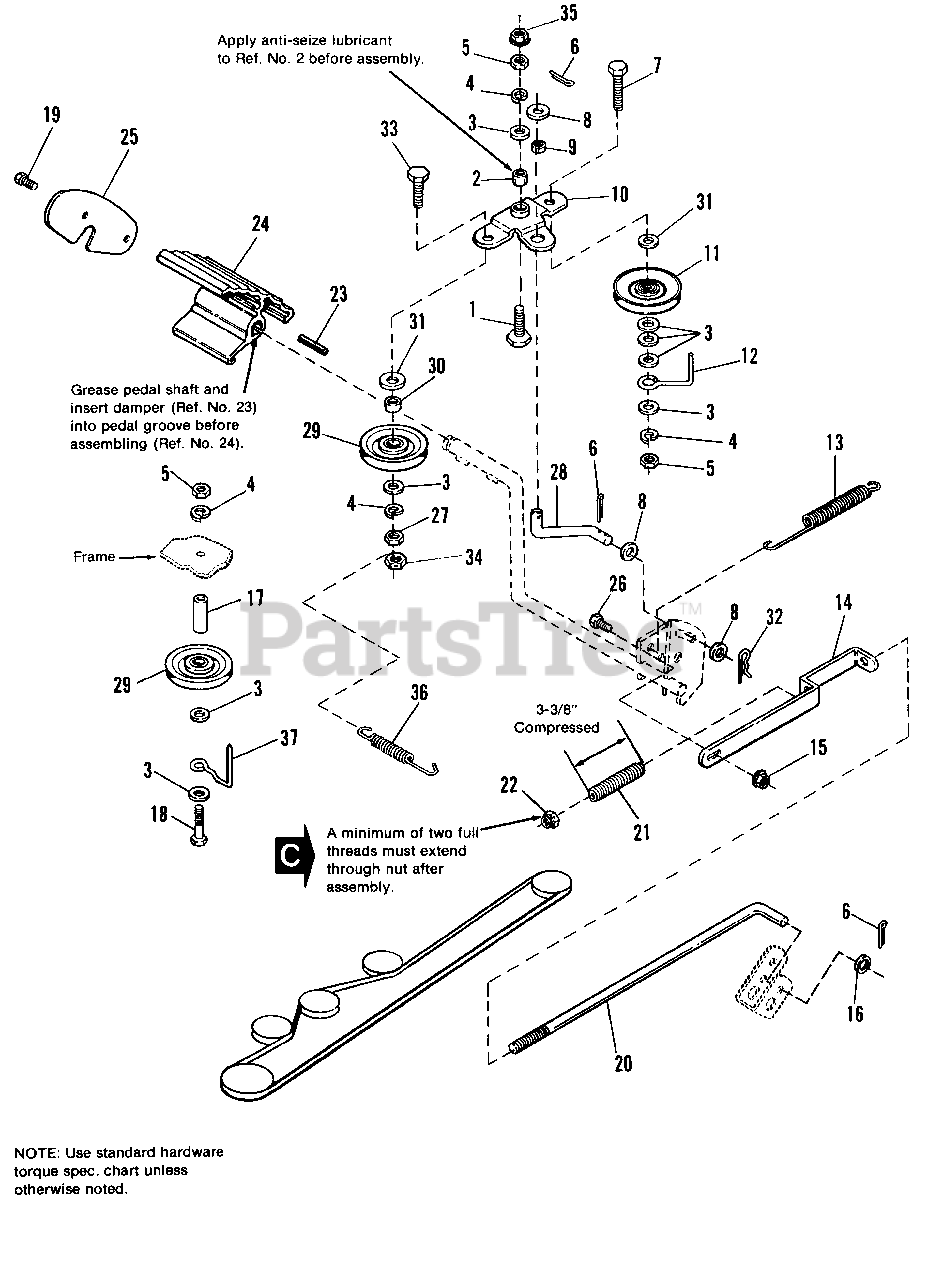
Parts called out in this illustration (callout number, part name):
1	SCREW, Hex, 3/8-16 x 1-1/4, Thin Hd.
3	WASHER, Plain, 5/16
4	LOCKWASHER, 3/8
5	NUT, Hex, 3/8-16
6	PIN, Cotter
7	CAPSCREW, Hex Hd., 3/8-16 x 1-3/4
8	WASHER, Plain, 13/32 x 7/8, 14 Ga.
9	BUSHING, Ball
10	ARM ASSY., Clutch
11	PULLEY, Idler
13	SPRING, Tension, Clutch
15	NUT, Hex, Flange Lock, 3/8-16
16	WASHER, 5/16
18	CAPSCREW, Hex, 3/8-16 x 3-1/4
19	SCREW, Taptite, 1/4-20 x 5/8
22	NUT, ESNA, Hex Jam, 5/16-18
23	DAMPER, Rubber
24	PEDAL, Foot
25	PLATE, End
26	CAPSCREW, Hex, 3/8-16 x 3/4
27	NUT, Hex, Jam, 3/8-16
28	LINK, Clutch Arm
29	PULLEY ASSY.
31	WASHER, 13/32 x 1, 10 Ga. Plain
32	CLIP, Spring
33	CAPSCREW, Hex Hd., 3/8-16 x 2-1/4
34	NUT, Hex Lock, Jam, 3/8-16
35	NUT, Hex Whizlock, 3/8-16
